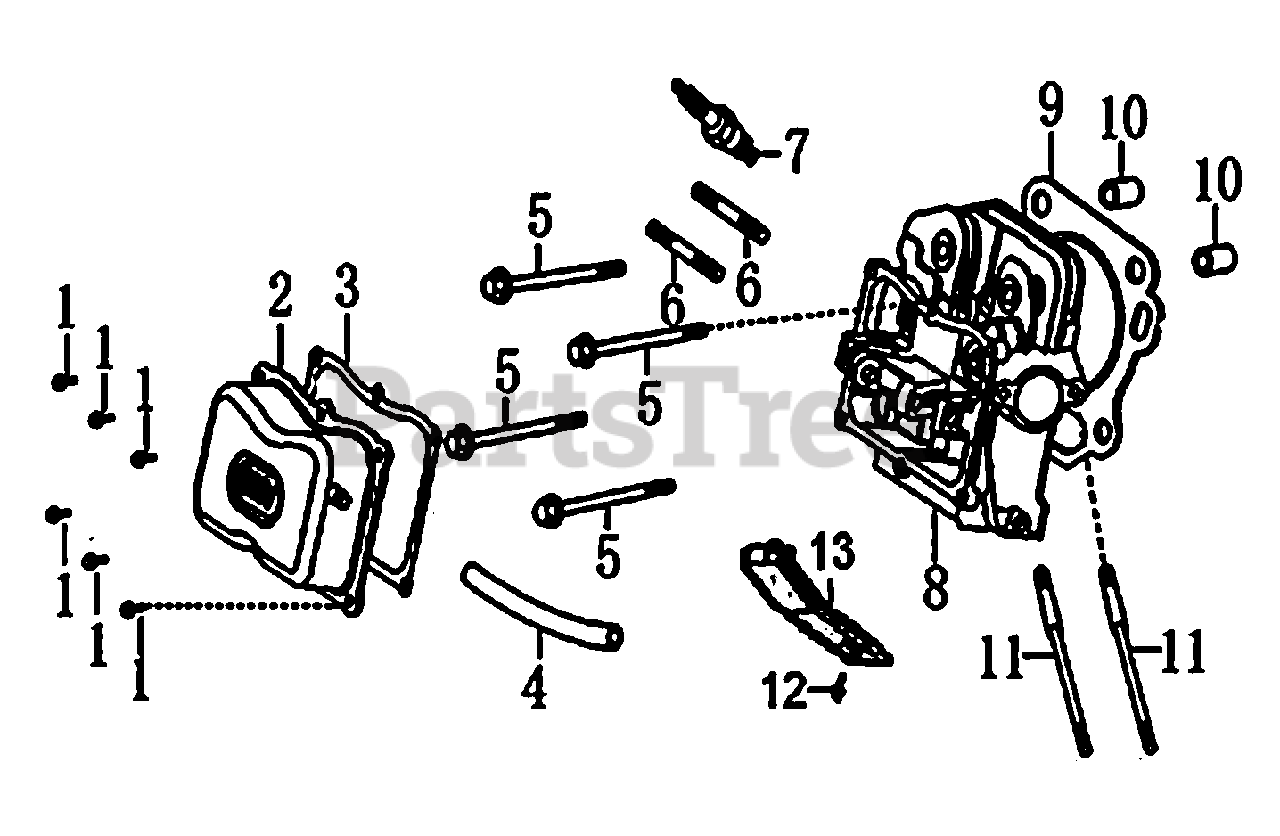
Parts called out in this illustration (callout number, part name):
1	BOLT, FLANGE
2	COVER, VALVE
3	GASKET, VALVE COVER
4	TUBE, BREATHER
5	BOLT, FLANGE, 10X80
6	BOLT, STUD, EXHAUST
7	SPARK PLUG
8	HEAD, CYLINDER
9	GASKET, CYLINDER HEAD
10	PIN, DOWEL
11	BOLT, STUD, INTAKE
12	BOLT, FLANGE M6X12
